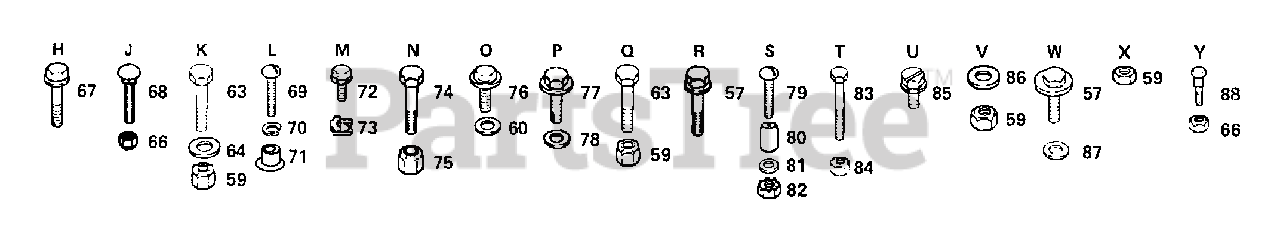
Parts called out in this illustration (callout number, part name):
57	SCREW
60	WASHER PM
63	BOLT
64	WASHER
68	BOLT
69	SCREW
70	WASHER LOCK #10
71	WELDNUT
73	"""J"" FASTENER LT"
74	BOLT T
76	SCREW HEX CRT
77	SCREW
78	WASHER M
79	SCREW
80	SPACER LT
81	WASHER
83	BOLT
84	NUT GTV
85	SCREW LT
86	WASHER
87	WASHER
